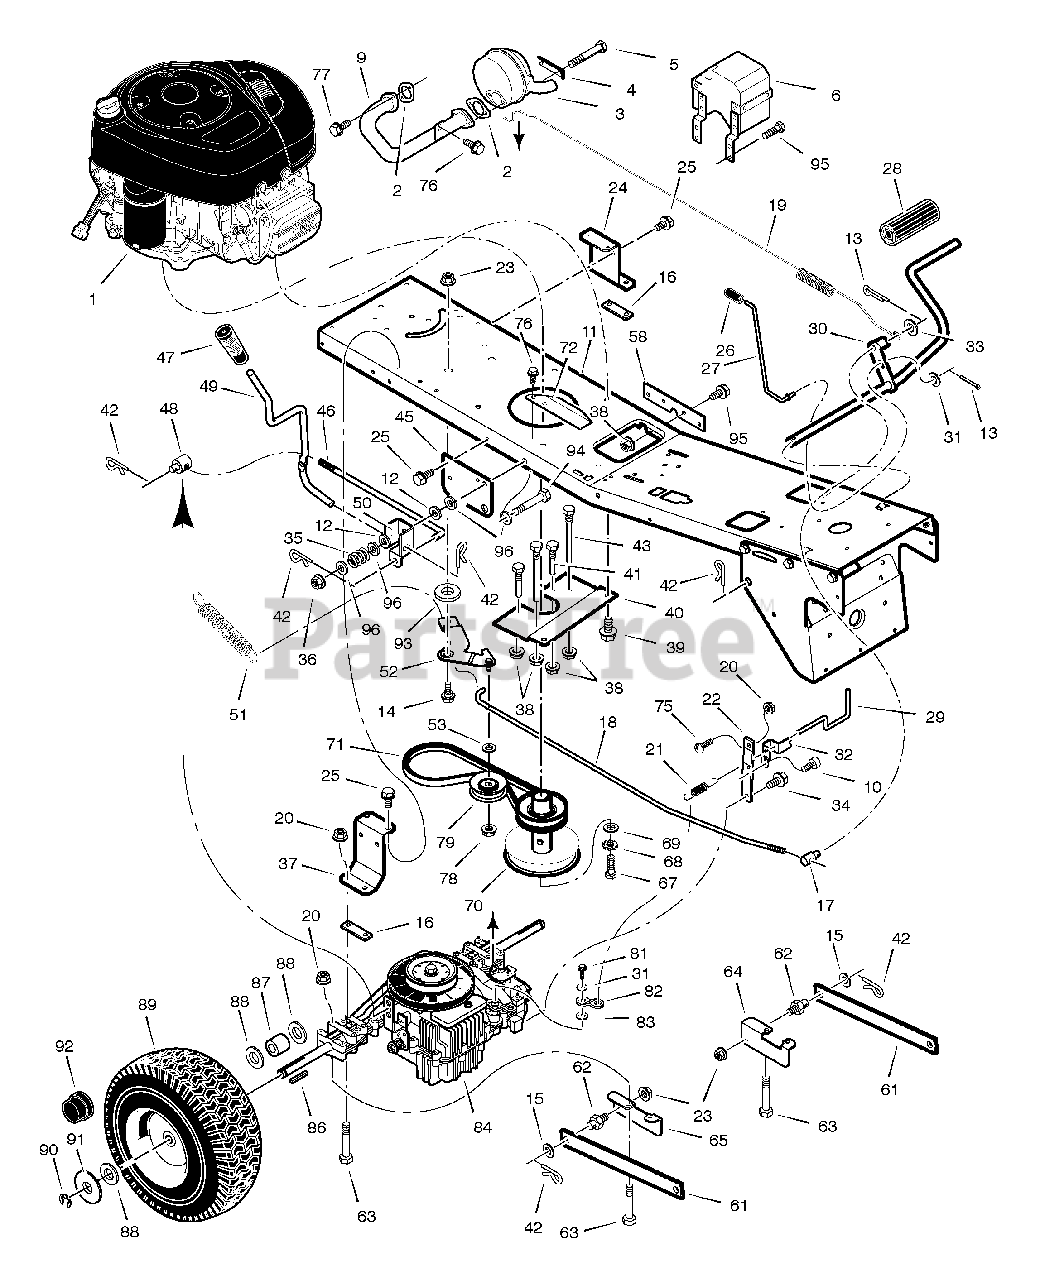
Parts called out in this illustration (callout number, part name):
1	Engine
2	GASKET, Exhaust
3	Muffler
4	Lock, Muffler Screw
5	Bolt, Hex
6	Shield, Heat
9	Tube, Exhaust
10	Screw
13	Pin, Cotter
14	Bolt, Shoulder
16	Plate, Transaxle
17	Nut, Adjusting
18	Rod, Clutch Hydro
19	Spring, Brake
20	Nut
21	Spring, Roll Release
22	Bracket, Torque Strap
23	Nut
24	Bracket, Left Transaxle
27	Rod, Parking Brake
28	Pedal
29	Rod, Roll Release
30	Rod, Clutch/Brake
32	Bracket, Roll Release
33	Washer
35	Spring, Compression
37	Bracket, Right Transaxle
38	Nut
39	Screw
40	Plate, Belt Guide
41	Guide, Belt -Long
42	Pin, Hair
43	Guide, Belt -Short
45	Bracket, Lift Pivot
46	Rod, Shift Link
47	Grip
48	Nut, Adjusting
49	Lever, Shift
50	Bracket, Pivot
51	Spring - Variator Drive
52	Arm, Idler
58	Plate, Reinforcement
62	Pin, Threaded
63	Bolt, Hex
64	Bracket, Left Rear Hanger
65	Bracket, Right Rear Hanger
67	Bolt, Hex
68	Lockwasher
70	Pulley Stack
71	Belt, Drive
72	Shield, Heat
75	Bolt, Carriage
78	Locknut
79	Pulley, Idler
81	Cap Screw
82	Arm, Disconnect
84	Transaxle
86	Key, Square
87	SPACER, Rear Wheel
89	Wheel & Tire Assembly
92	Hub Cap
93	Washer
94	Bolt, Hex
96	Washer
